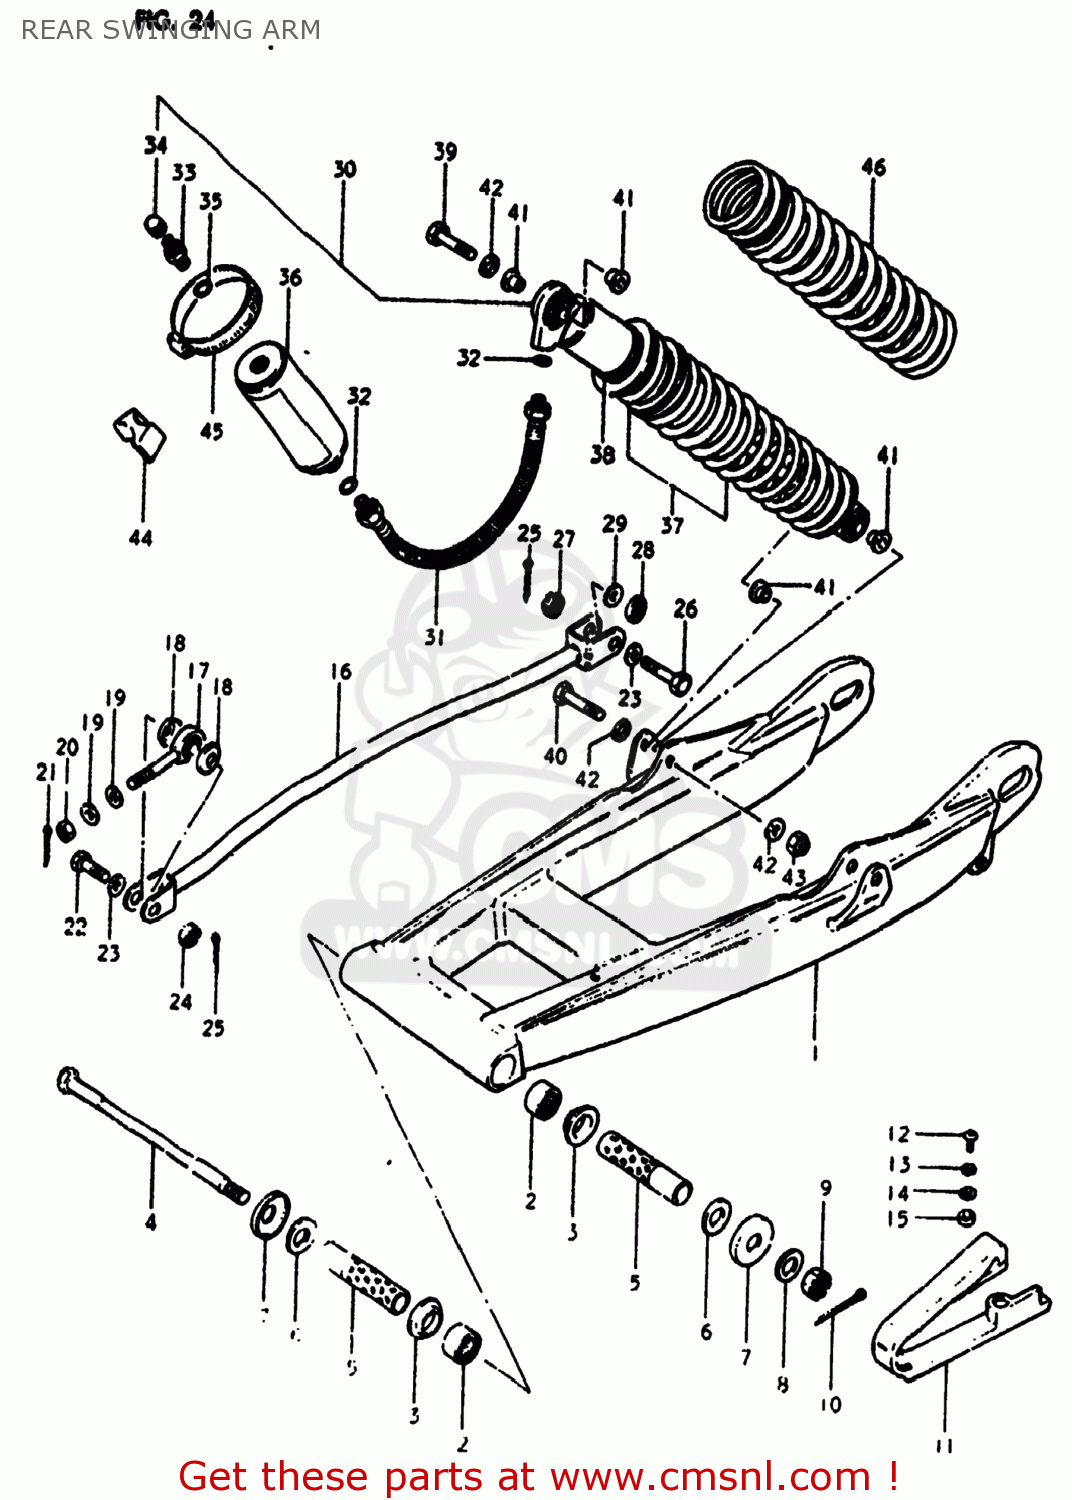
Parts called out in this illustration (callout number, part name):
1	SWING ARM ASSEMBLY,REAR
2	BEARING
3	BUSHING,REAR SWING ARM PIVOT
4	SHAFT,REAR SWING ARM
5	SPACER,REAR SWING ARM
6	WASHER
7	COVER,RR SWGARM DUST SEAL
8	WASHER
9	NUT 14MM
10	COTTER PIN
11	BUFFER,CHAIN TOUCH DEFENSE
12	SCREW
13	LOCK WASHER
14	WASHER
15	SPACER (5.5X8X4)
16	LINK,REAR TORQUE
17	BEARING
18	DUST SEAL,TORQUE LINK FR BRG
19	WASHER
20	NUT
21	PIN
22	BOLT 8X28
23	WASHER
24	NUT 8MM
25	PIN 20X20
26	BOLT 8X35
27	NUT 8MM
28	29
29	WASHER (8.5X16X2.6)
30	ABSORBER ASSEMBLY,REAR SHOCK
31	HOSE,REAR SHOCK ABSORBER
32	O-RING,RESERVE TANK
33	VALVE
34	CAP,VALVE AIR
35	O RING
36	RESERVE TANK,REAR SHOCK
38	STOP, SPRING
39	BOLT
40	BOLT(8X46)
41	SPACER,RR SHK ABS INNER
42	WASHER
43	NUT
44	CUSHION,RR SHOCK ABSORBER
45	CLAMP
